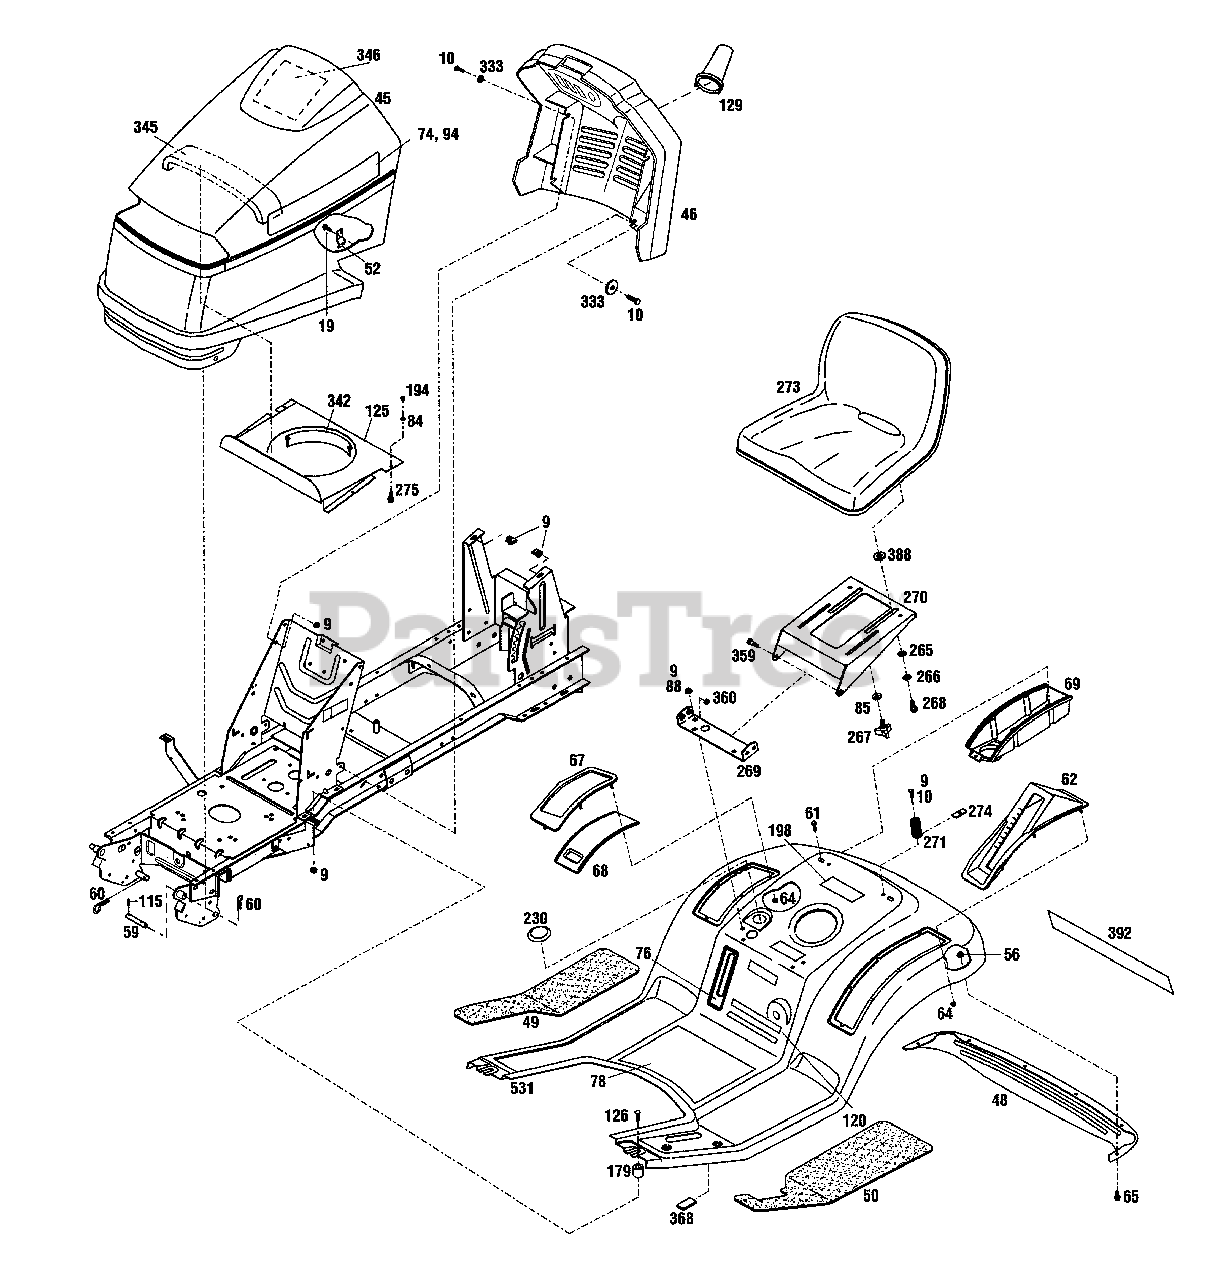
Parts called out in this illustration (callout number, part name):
9	Flange Nut, 5/16-18
10	Hex Head Screw, 5/16-18 x 3/4
19	Self Threading Screw, #10
46	Console
48	Rear Fender Trim
49	Right Foot Pad
50	Left Foot Pad
52	Latch
56	Flange Nut,1/4-20
59	Hood Pivot Pin
60	Cotter Spring, 1/8
61	Screw, 5/16-18 x 7/8
62	Lift Handle Cover
64	Self-Threading Nut, 1/4
65	Flange Screw, 1/4-20 x 1/2
67	Storage Top
68	Container Cover
69	Storage Container
74	Logo Decal, L.H.
76	Fuel Level Decal
78	Tunnel Decal
84	Lockwasher, 1/4 SAE
85	Flat washer, 3/8
88	Carriage Bolt, 5/16-18 x 5/8
94	Logo Decal, R.H.
115	Drive Pin, 3/16 x 1
120	Height Indicator Decal
125	Upper Heat Shield
126	Carriage Bolt, 5/16-18 x 3/4
129	Steering Cover
179	Spacer
194	Hex Nut, 1/4-20
198	Fuel Decal
265	Nylon Washer, 3/8
266	Bowed Washer, 3/8
267	Adjusting Knob
268	Shoulder Bolt, 3/8-18 x 1/2
269	Seat Bracket
270	Seat Support
271	Compression Spring
273	High Back Seat
274	Spring Hold-Down Bracket
275	Screw, 1/4-20 x 5/8
333	Flat Washer, 5/16 x 1-1/2
342	Heat Shield Gasket
345	Sealing Strip
346	Service Decal
359	Hex Head Screw, 3/8-18 x 7/8
360	Locknut, 3/8-16
388	Flat Washer, 3/8
392	Decal, Model
531	Rear Fender
